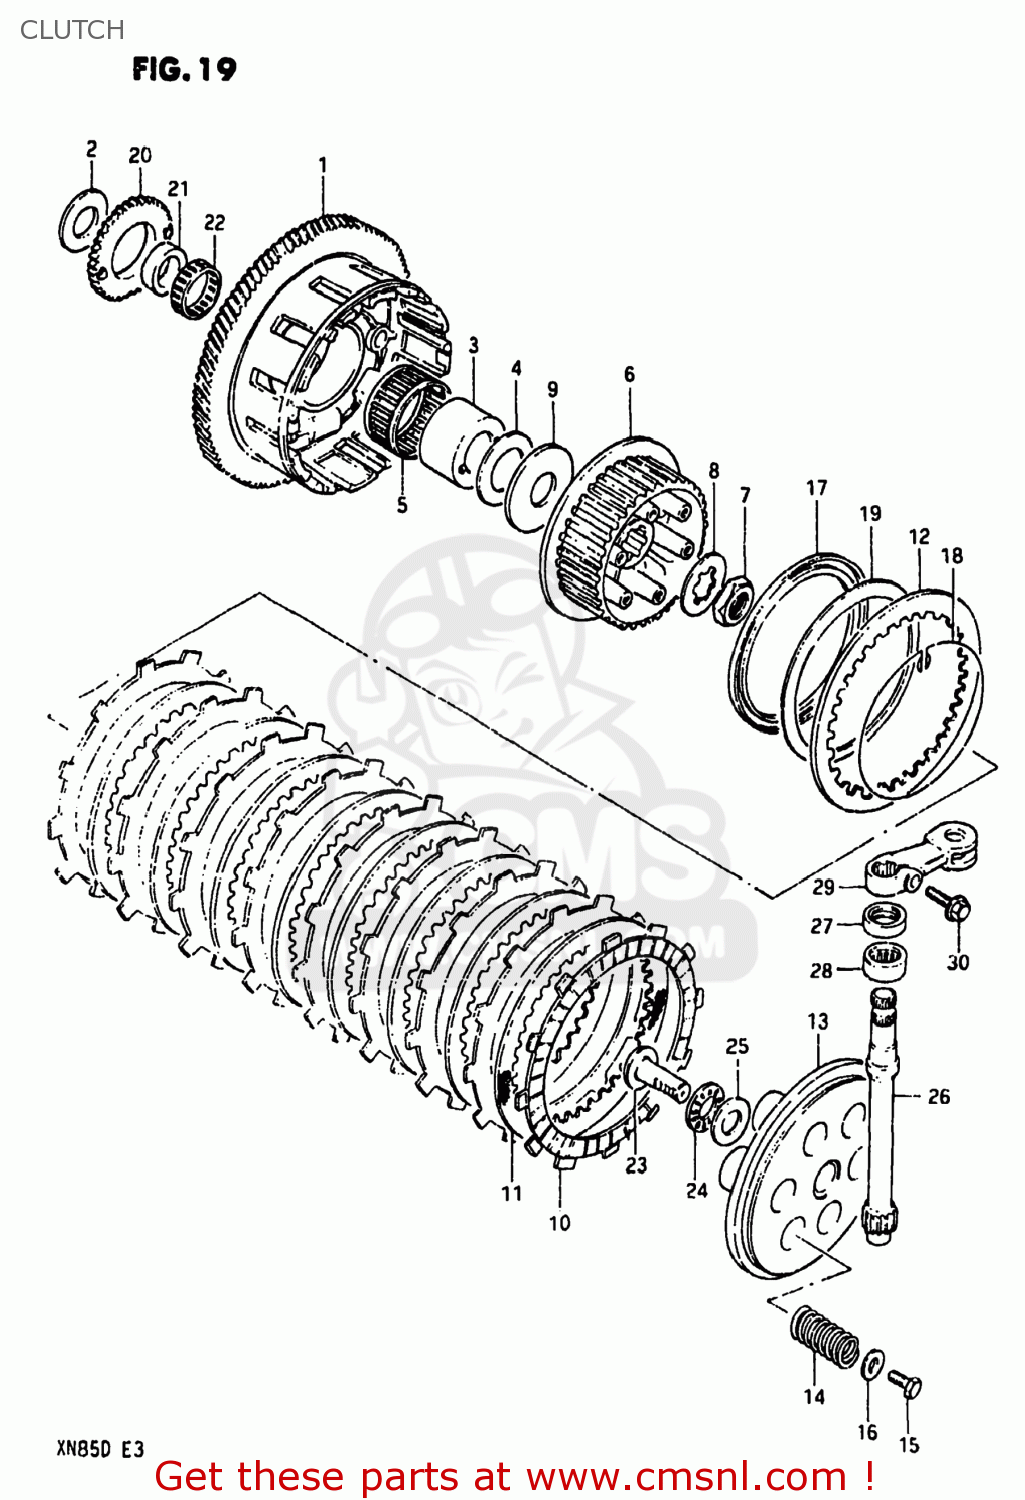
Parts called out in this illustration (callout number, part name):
1	GEAR ASSEMBLY,PRIMARY DRIVE
2	WASHER
3	SPACER
4	SHIM(T:1.00)
5	BEARING
6	HUB,CLUTCH SLEEVE
7	NUT
8	WASHER,LOCK
9	WASHER(25X66X3.5)
10	PLATE,CLUTCH DRIVE (MCA)
11	PLATE,CLUTCH DRIVEN (NAS)
12	PLATE,CLUTCH DRIVEN(T:2.0) (NAS)
13	DISC,CLUTCH PRESSURE
14	SPRING
15	BOLT, UPPER
16	WASHER
17	SEAT,WAVE WASHER
18	RING,STOPPER
19	WASHER
20	GEAR,ENG OIL PUMP DRIVE(NT:34)
21	SPACER,OIL PUMP DRIVE GEAR
22	BEARING(36X40X10)
23	RACK,CLUTCH RELEASE
24	BEARING(15X28X2)
25	WASHER
26	PINION,CLUTCH RELEASE
27	OIL SEAL
28	BEARING(15X22X12)
29	ARM,CLUTCH RELEASE
30	BOLT (6X20)
